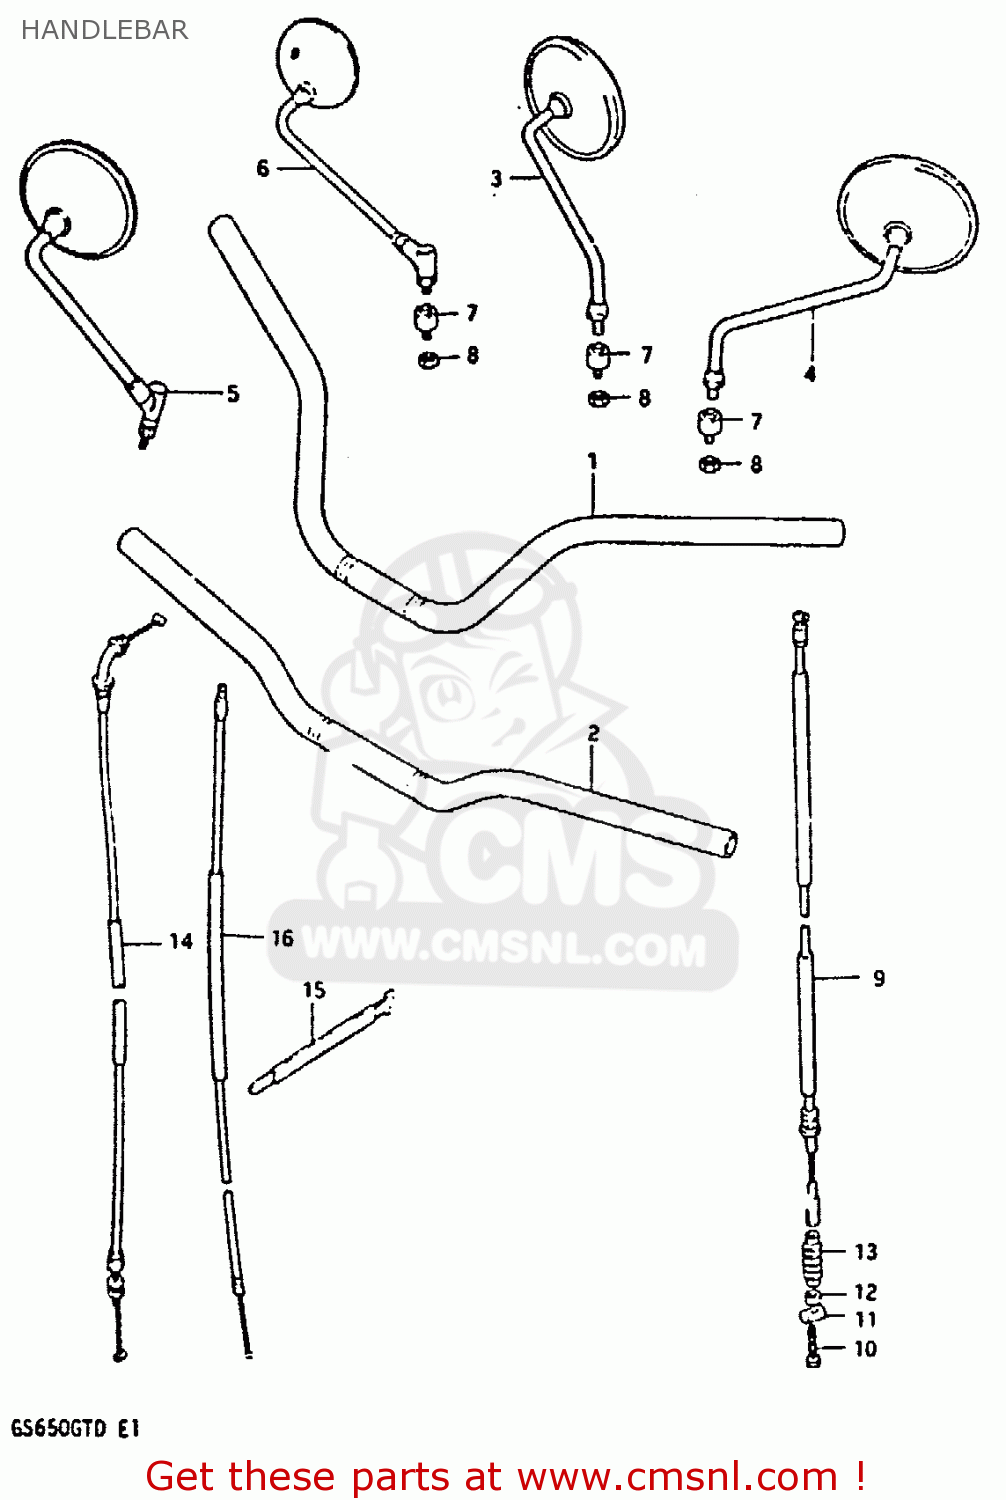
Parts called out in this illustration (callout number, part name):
1	HANDLEBAR (NERTRAL)
2	HANDLEBAR (FLAT)
5	MIRROR ASSY,RH
7	CUSHION,REAR VIEW MIRROR
8	NUT
9	CABLE, CLUTCH (FLAT)
10	SCREW
11	PIN
12	NUT
13	SEAL,DUST(6.5X16X91)
14	CABLE ASSEMBLY,THROTTLE
15	CLAMP
16	CABLE COMP,STARTER
